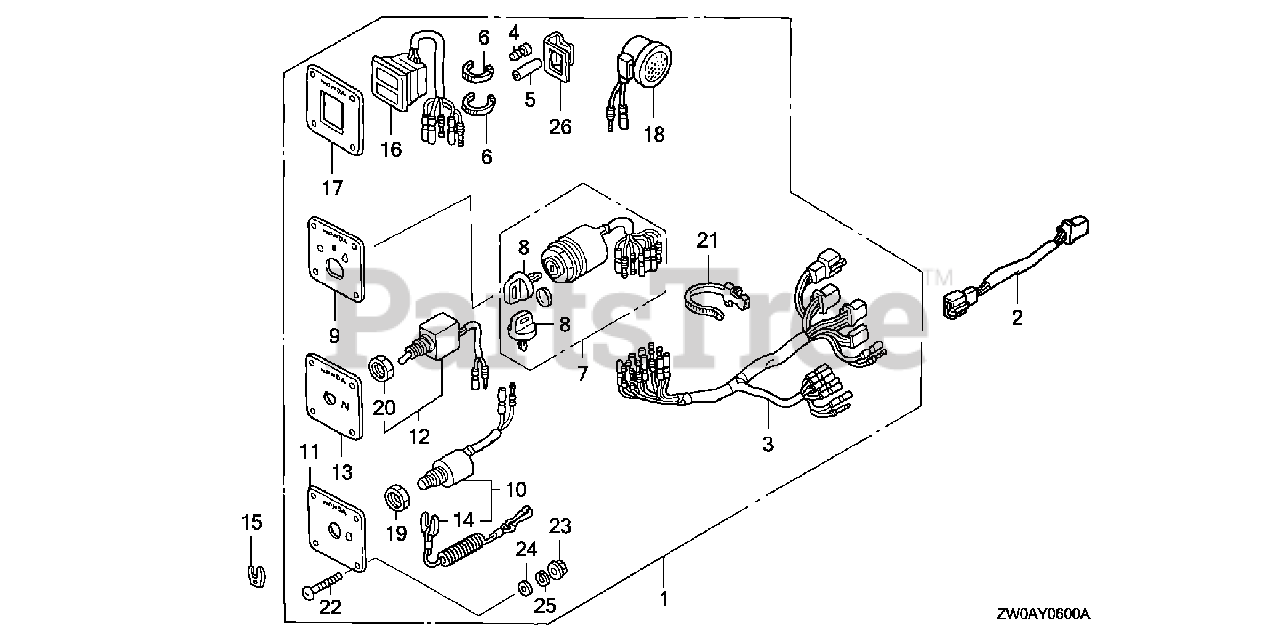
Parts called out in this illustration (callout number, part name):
1	PANEL KIT, CONTROL (B)
2	SUB-HARNESS ASSY., POWER
3	HARNESS ASSY., SWITCH PANEL
4	PLUG, CONNECTOR (INNER)
5	PLUG, CONNECTOR (OUTER)
6	TIE, CABLE (NATURAL 2.4X92)
7	SWITCH ASSY., COMBINATION
8	KEY ASSY., COMBINATION SWITCH
9	PANEL, SWITCH
10	SWITCH ASSY., EMERGENCY STOP
11	PANEL, EMERGENCY STOP SWITCH
12	SWITCH ASSY., SOLENOID
13	PANEL, SOLENOID
14	WIRE, EMERGENCY
15	CLIP, EMERGENCY LOCK
16	LAMP ASSY., INDICATOR (2-LED)
17	PANEL, INDICATOR
18	BUZZER, WARNING
19	NUT, HEX. (16MM)
20	NUT, HEX. (12MM)
21	BAND, WIRE HARNESS (150MM)
22	SCREW, PAN (5X40)
23	NUT, FLANGE (5MM)
24	WASHER, PLAIN (5MM)
25	WASHER, SPRING (5MM)
26	BRACKET, BUZZER
